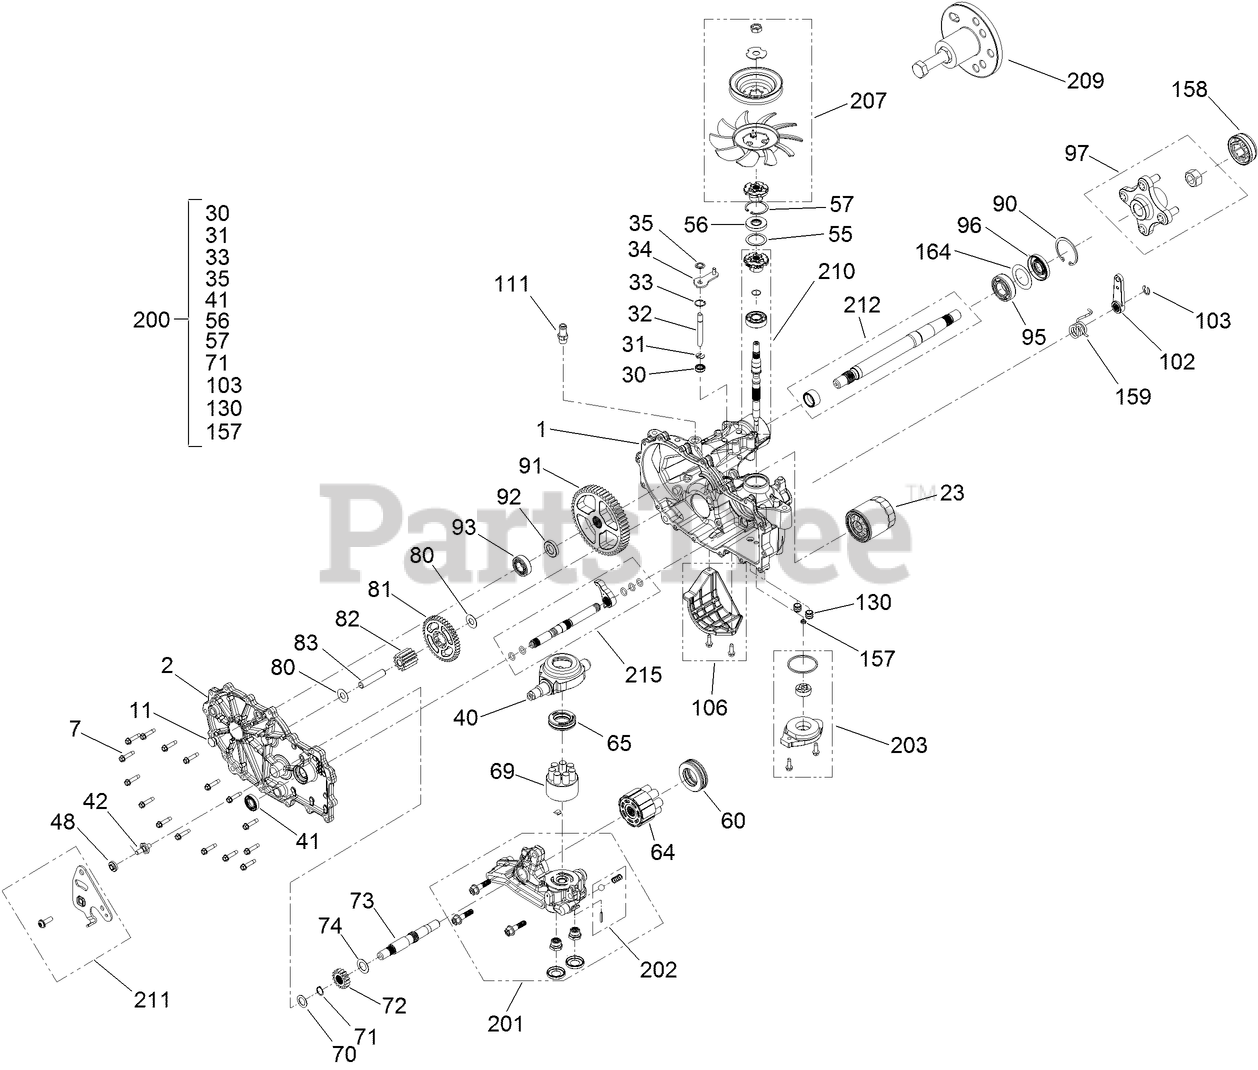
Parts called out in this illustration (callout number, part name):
1	KIT, MAIN HOUSING LH, CHARGE
2	KIT, SIDE COVER LH, CONTROL
7	SCREW-HHF
23	ELEMENT-OIL FILTER, HYD
30	SEAL-LIP
31	RING-RETAINING, EXTERNAL
32	ROD-BYPASS
33	RING-RETAINING, INTERNAL
35	RING-RETAINING, EXTERNAL
40	SWASHPLATE-TRUNNION
41	SEAL-LIP
48	SPACER
55	SPACER
56	SEAL-LIP
57	RING-RETAINING
60	BEARING-THRUST
64	CYLINDER BLOCK ASM KIT
65	BEARING-THRUST
69	PUMP BLOCK ASM
70	WASHER-FLAT
71	RING-RETAINING
72	GEAR-16T
73	SHAFT-MOTOR
74	WASHER
80	WASHER
81	GEAR-43T
82	GEAR-11T
83	PIN-JACKSHAFT
90	RING-RETAINING
91	GEAR-54T
92	SPACER
93	BEARING-BALL
95	BEARING-BALL
97	HUB KIT
102	HANDLE-BRAKE
103	RING-RETAINING, EXT
106	GUARD-FILTER, LH
111	ADAPTER-STRAIGHT
130	TUBE-CHARGE
157	COVER-NUT, AXLE
158	GEROTOR SEAL KIT
159	SPRING, TORSION, CW
164	SPACER
200	SEAL KIT
201	LH CHARGE CENTER SECTION KIT
202	CHARGE RELIEF KIT
203	CHARGE KIT
207	FAN AND PULLEY KIT
209	HUB PULLER KIT
210	INPUT SHAFT KIT
211	SPRING, TORSION, CW
212	AXLE SHAFT KIT
215	KIT, OUTBOARD, RH ROT B/LH ROT A
